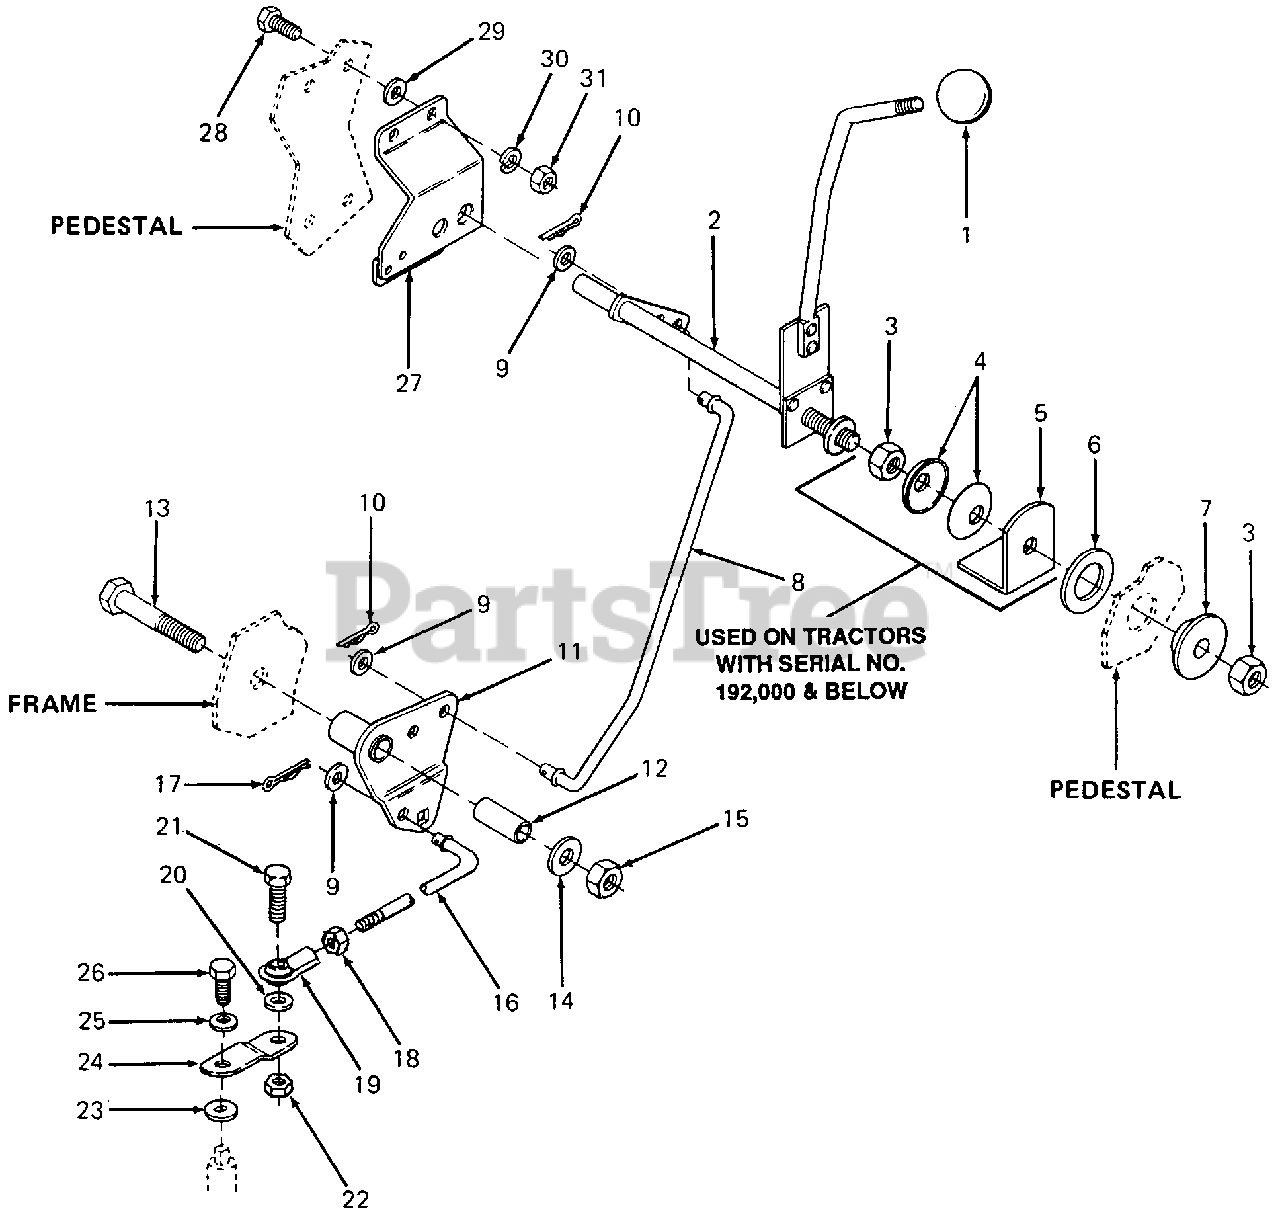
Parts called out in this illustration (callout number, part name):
1	Knob, Control
2	Shifter Assy
3	Nut, Hex Top Lock, 1/2-20
4	Washer, Bell
5	Bracket, Friction
6	Washer, Friction
7	Spacer, Shoulder
8	Rod, Shift
9	Washer, Flat, .406 X .75 X.063 Thk
10	Pin, Cotter, 1/8 X 1.0 Lg
11	Cam, Shift
12	Sleeve, .380 X .623 X 1.555 Lg
13	Screw, Hex Cap, 3/8-16 X 2.25 Lg GR5
14	Washer, Flat, .385 X .87 X 0.6 Thk HDN
15	Nut, Hex Center Lock, 3/8-16
16	Rod, Shift
17	Pin, Internal Cotter
18	Nut, Hex Jam, 3/8-24
19	Ball Joint
20	Washer, Flat, .385 X .62 X .063 Thk
21	Screw, Hex Cap, 3/8-24 X 1.0 Lg
22	Nut, Hex Center Lock Jam, 3/8-24
24	Bracket, Shifter
25	Washer, Bell, .265 X .75 X .062 Thk
26	Screw, Hex Patch Lock, 1/4-28 X .62 Lg
27	Bracket, Clutch Handle
28	Screw, Hex Cap, 1/4-20 X .62 Lg GR5
29	Washer, Flat, .281 X .75 X .105 Thk
30	Washer, Lock, 1/4
31	Nut, Hex, 1/4-20 GR5
